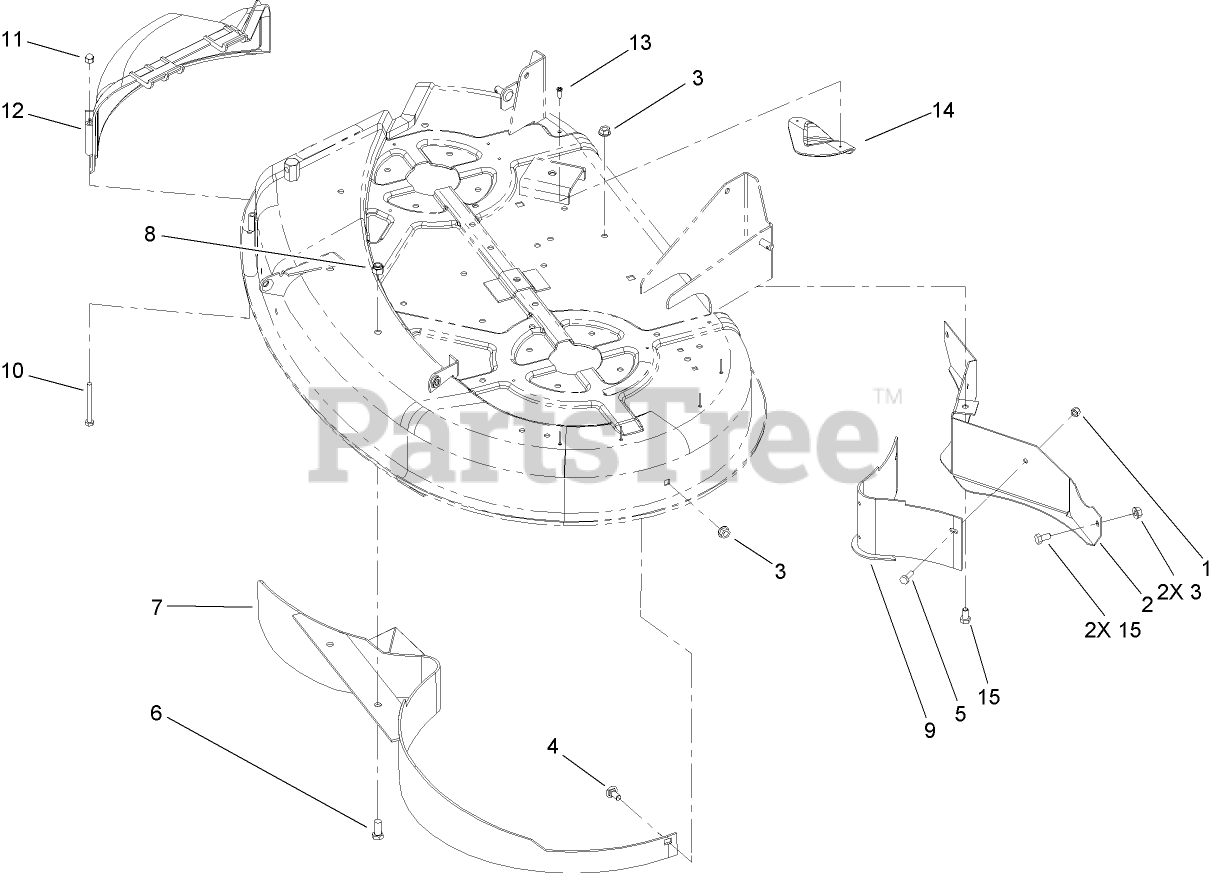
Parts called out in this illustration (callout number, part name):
1	NUT-LOCK, NI
2	BAFFLE-REAR
3	NUT-HF
4	BOLT-CARR
5	SCREW-HH
6	SCREW-HH
7	BAFFLE ASM
8	NUT-LOCK, NI
9	BAFFLE ASM
10	SCREW-HH
11	NUT-CAP
12	COVER-RECYCLER
13	SCREW-PPH
14	PLATE-KICKER
15	SCREW-HH
